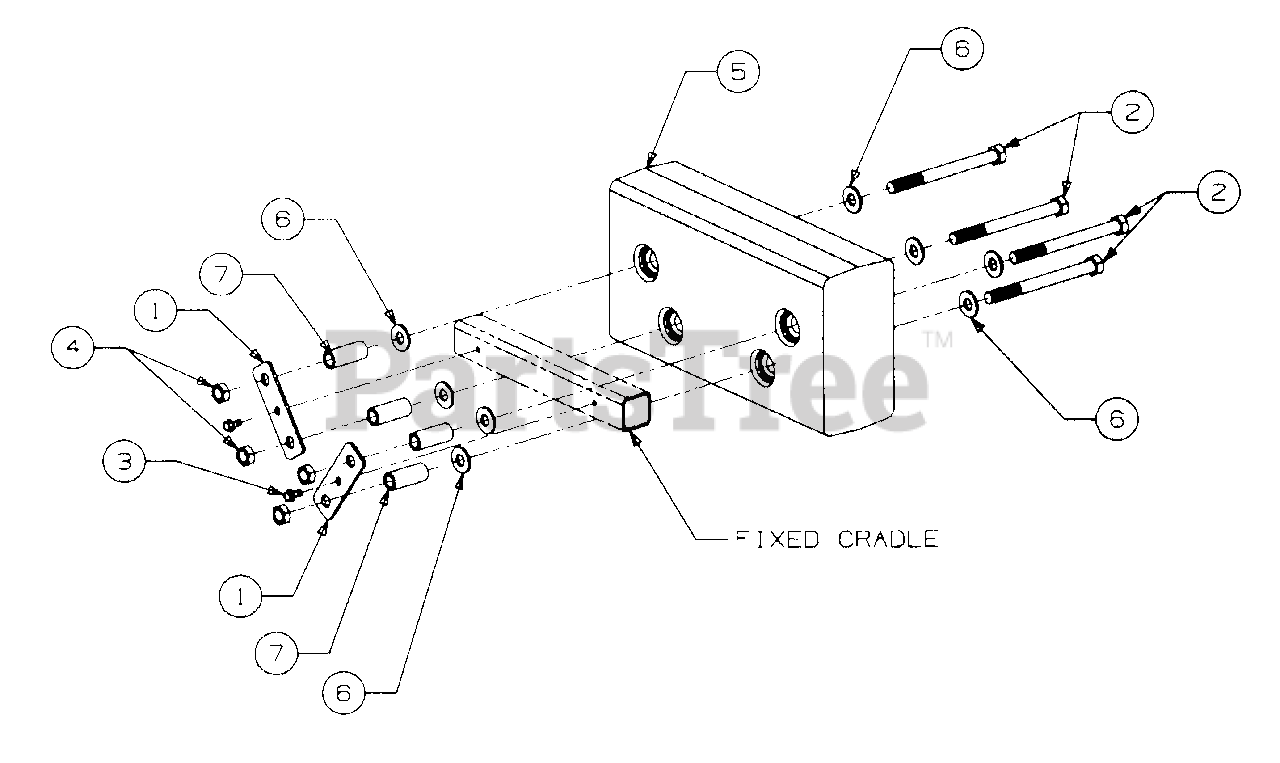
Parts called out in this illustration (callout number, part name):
3	Screw, Hex Wash Hd TT-Tap, 1/4-20 X .50 Lg
4	Nut, Hex Top Lock Jam, 1/2-20 GR5
5	Weight, Counter, 38 Lbs
6	Washer, Flat, .515 X 1.12 X .100 Thk Hdn
7	Spacer, .505 X .75 X 1.75 Lg
